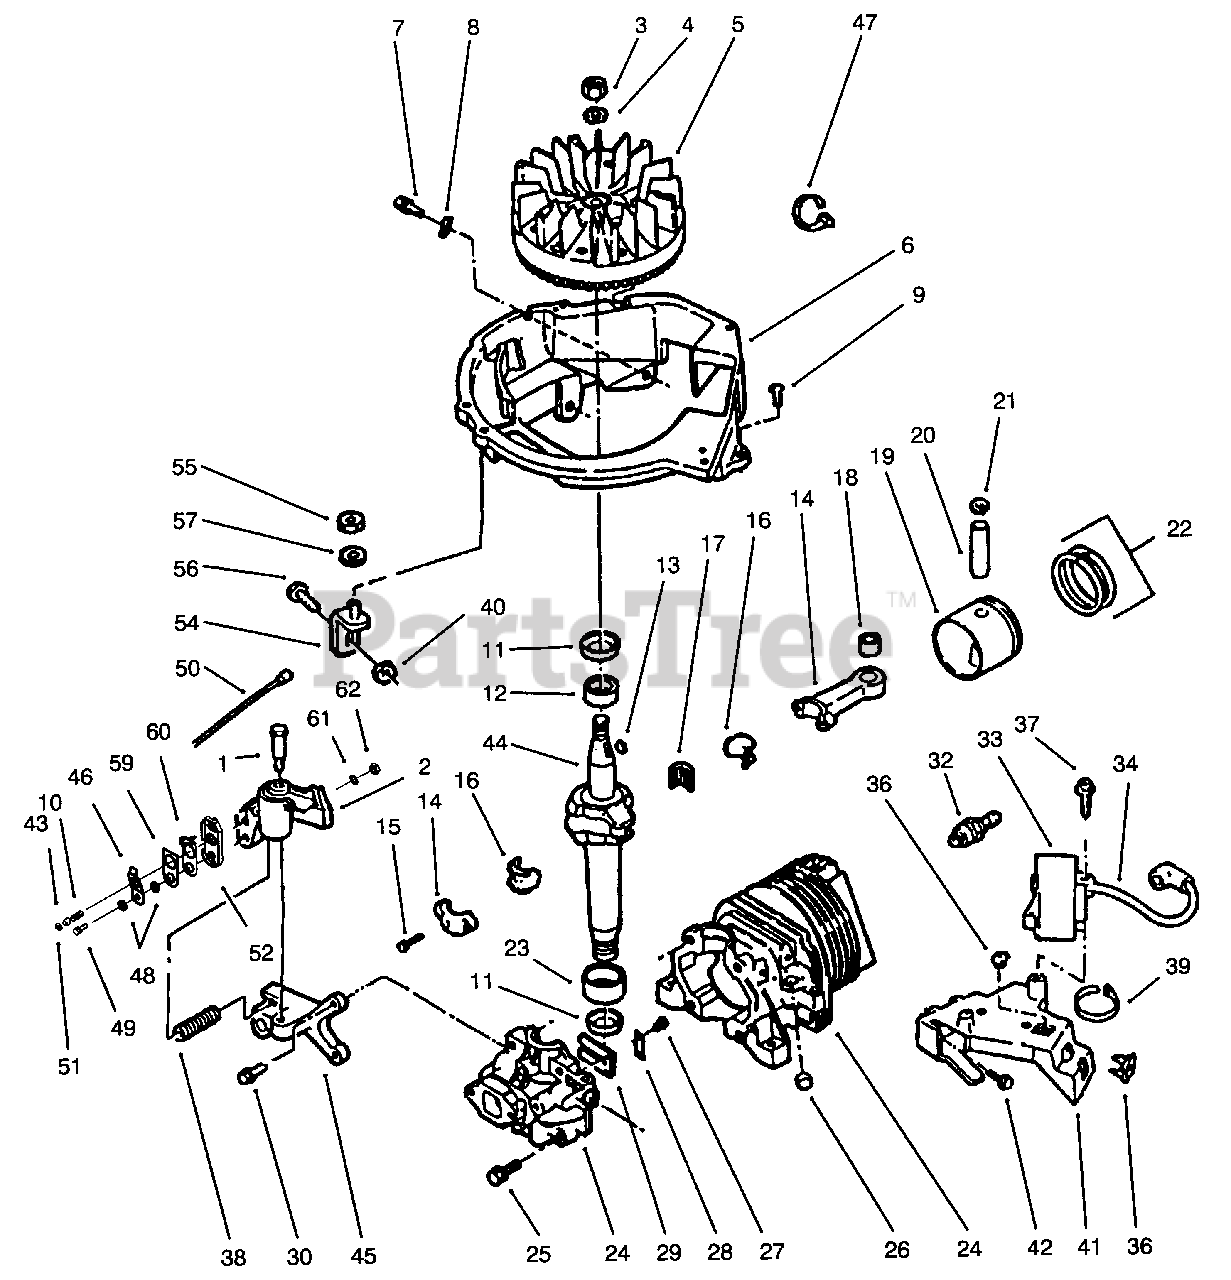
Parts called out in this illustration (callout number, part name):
1	Bolt-Shoulder
2	Brake Assembly
3	Nut-Flywheel
4	Lockwasher
5	Flywheel Assembly
6	Base-Shroud
8	Clip-"J"
10	Spring-Cable Return
11	Oil Seal
12	Bearing-Main-Upper
13	Key-Flywheel
14	Connecting Rod Assy. (Inc 15-18)
15	Screw-Cap
16	Liner-Pair
17	Needle Bearing Set
18	Bearing Assembly
19	Piston & Ring Set (Inc 20-22)
20	Wrist Pin
21	Retaining Ring
22	Ring Set
23	Bearing-Main-Lower
24	Cylinder & Crankcase Cover Assy. (Inc. 25-30)
25	Screw-Cover to Crankcase
27	Screw-Reed to Crankcase Cover
28	Plate-Reed Hold Down
30	Screw-Brake Mounting Bracket
32	Spark Plug
33	C.D. lgnition Module & Lead Assy (Incl. Ref. #34)
34	High Tension Lead & Cover
36	Grommet
37	Screw-C.D. Mounting
38	Spring-Brake
39	Tie Strap
41	Bracket-C.D. Mounting
43	Actuator-Brake Lever
44	Crankshaft
45	Bracket-Brake
47	Tie Strap
48	Washer
49	Screw-Hex Hd. Cap
50	Lead Assembly
51	Retainer
52	Case-Switch
54	Brace Assembly
57	Washer
60	Plate-Contact
61	Washer-Lock
62	Nut
